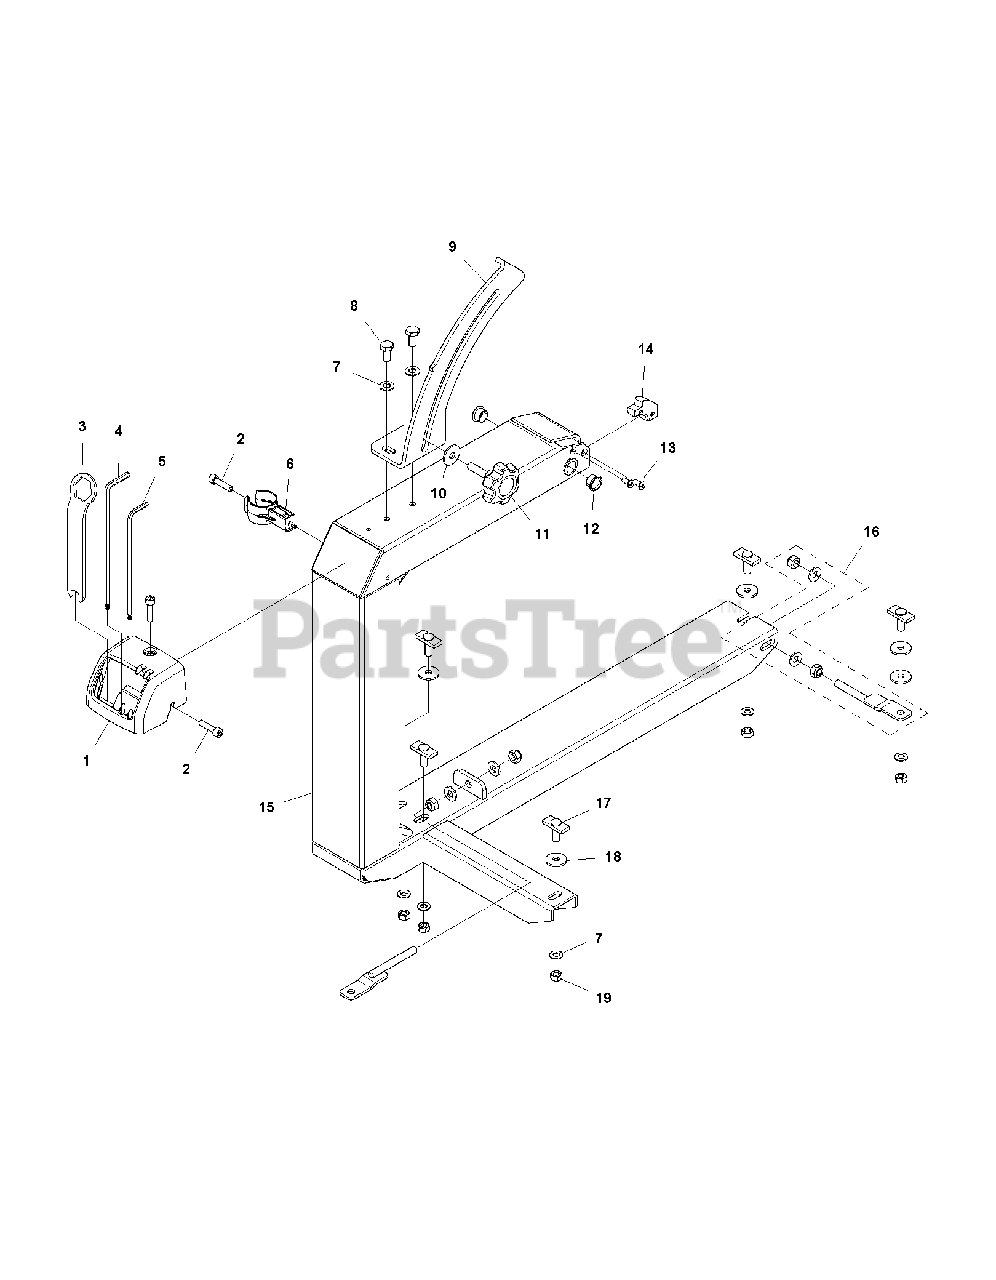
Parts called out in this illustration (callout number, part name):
2	SCREW IHSCM
7	WASHER
8	SCREW EHHM
19	HEXAGON LOCKING NUT
